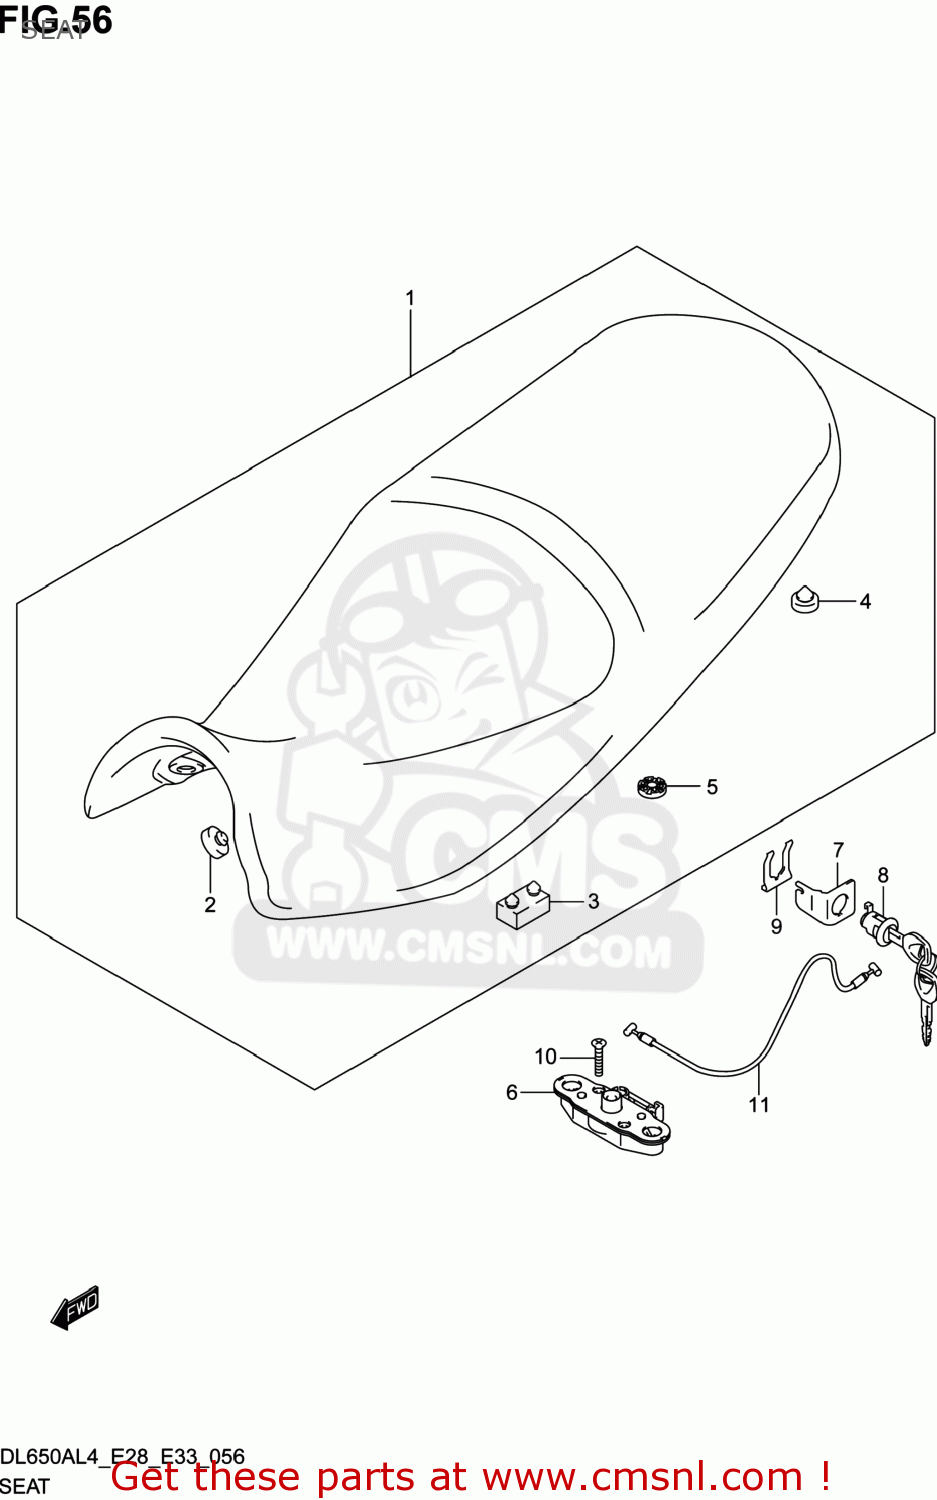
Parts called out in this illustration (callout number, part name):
1	SEAT ASSY
2	CUSHION,SEAT
3	CUSHION,SEAT(40X20X15)
4	CUSHION
5	CUSHION,SEAT LOCK(10X22X6)
6	BRACKET,SEAT SUPPORT
7	GUIDE,SEAT LOCK CABLE
8	LOCK SET,SEAT
9	PLATE,SEAT LOCK ASSY
10	SCREW
11	CABLE,SEAT LOCK
